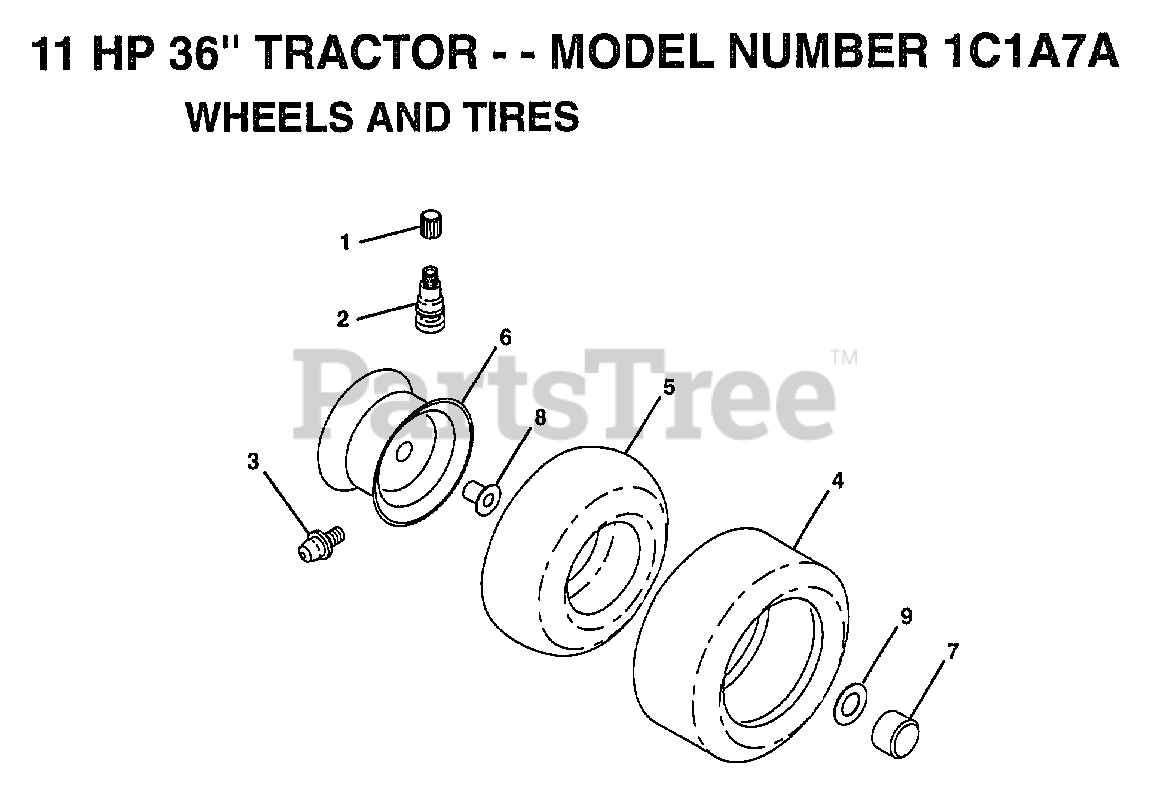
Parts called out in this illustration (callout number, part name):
1	VALVE CAP
2	VALVE STEM LT
3	FITTING LT
5	TUBE.5.3/4.5/6
5	TUBE.16X6.5/7.5-8
6	"RIM ASM REAR 8"""
7	HUB CAP
8	"FLANGE, BEARING"
9	WASHER
